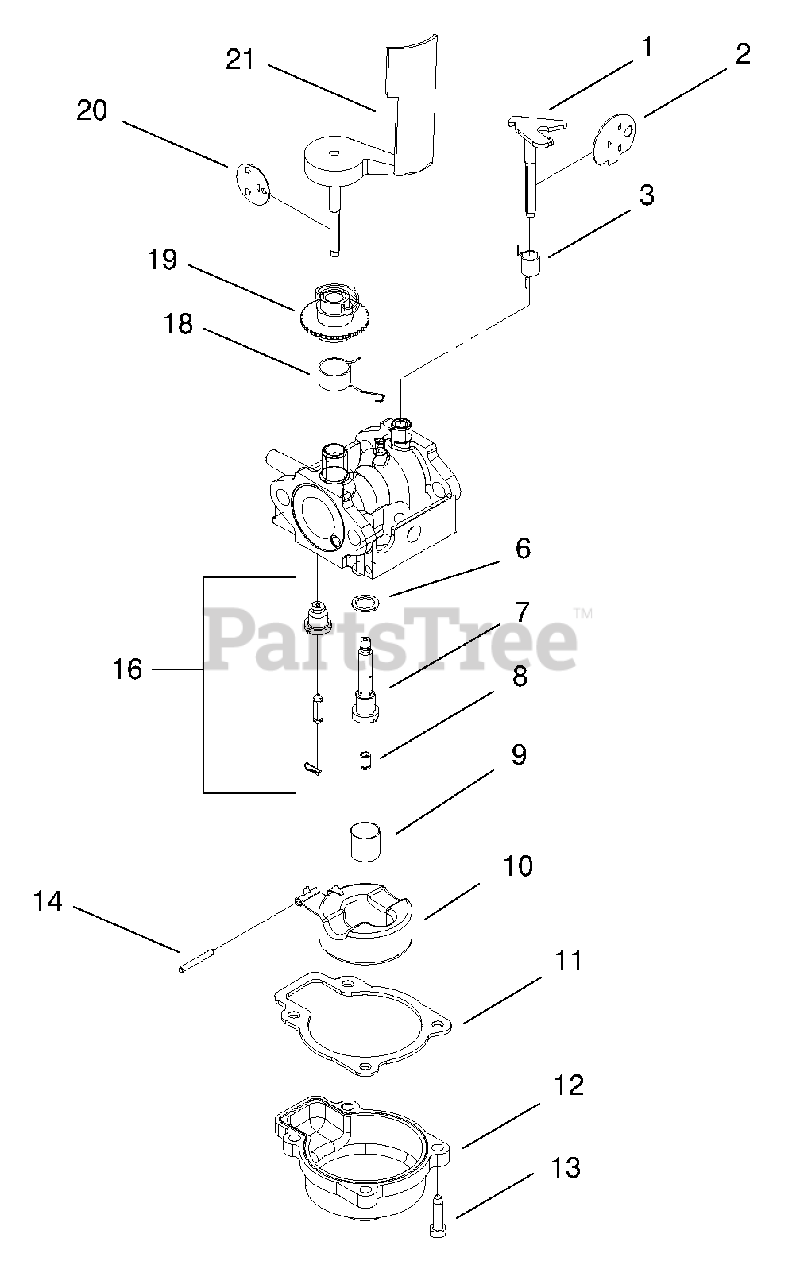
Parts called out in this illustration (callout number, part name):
1	Shaft-Choke
2	Disc-Choke
3	Spring-Choke
8	Jet-Main
9	Filter-Fuel
10	Float & Arm ASM
12	Chamber-Float
13	Screw-HH
14	Pin-Straight
16	Valve/Seat-Float
18	Spring-Throttle
19	Collar-Adjust, Airvane
20	Disc-Throttle
21	Air Vane & Shaft
